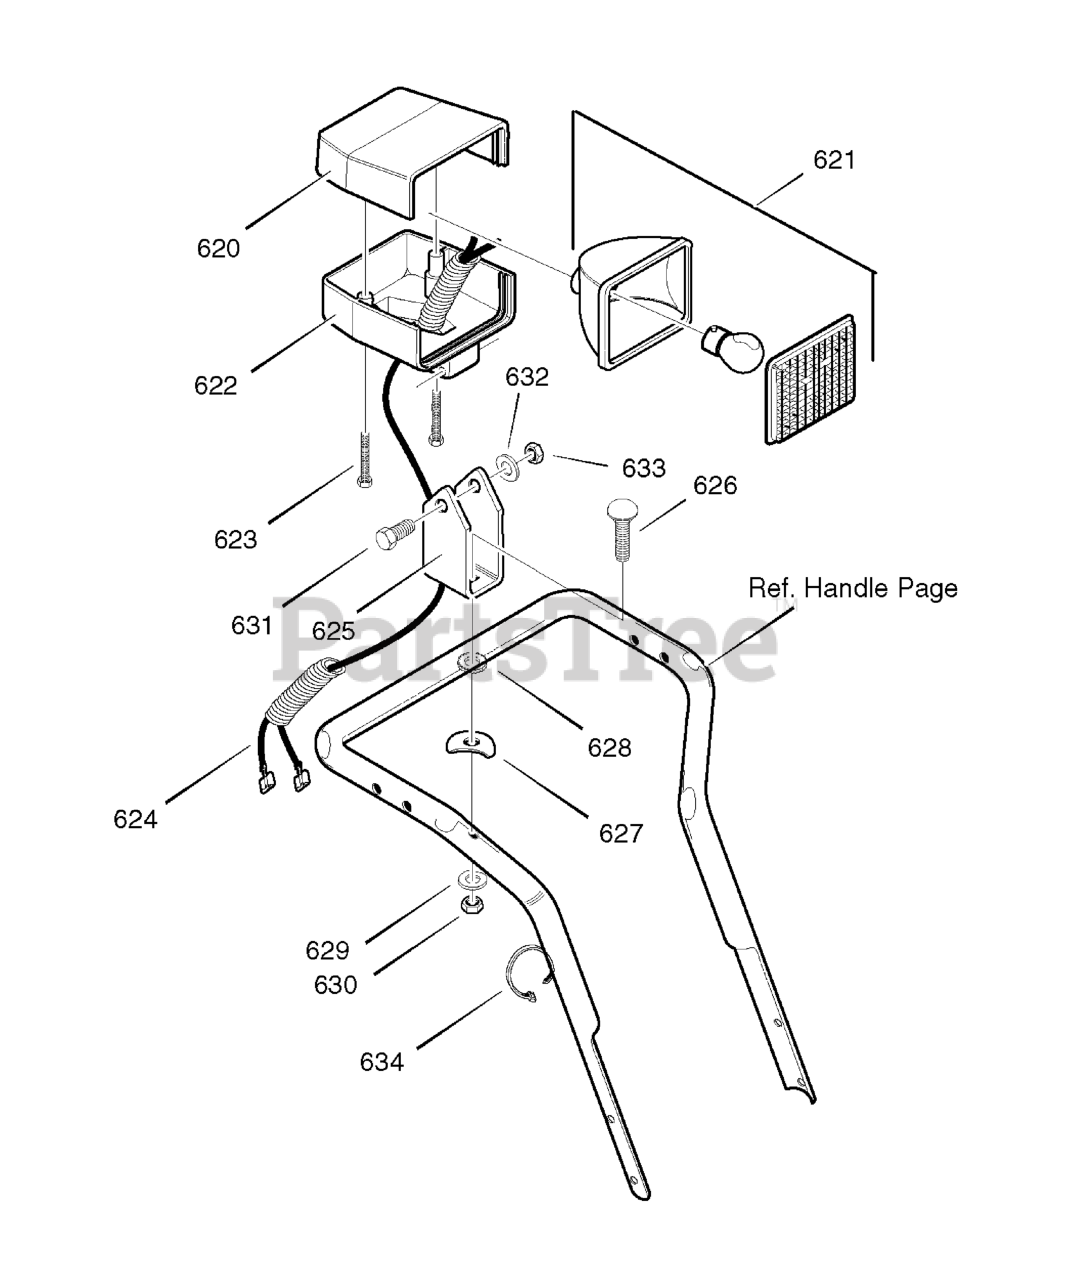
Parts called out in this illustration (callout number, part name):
620	HOUSING, HEADLIGHT UPPER
621	HEADLIGHT ASSEMBLY *
622	HOUSING, HEADLIGHT LOWER
623	SCREW, #8 X 1.75
624	WIRING HARNESS, HALOGEN
625	BRACKET, HEADLIGHT
626	BOLT, CARRIAGE - 5/16-18 X 2.00
627	WASHER, SADDLE
628	WASHER, EXLK .32 X .60 X .040
629	WASHER, SPTLK .31 X .58 X .08
630	NUT, 5/16-18 REGHEX
631	SCREW, 5/16-18 x 2.00
632	WASHER, SPTLK
633	NUT, 5/16- 18 REGHEX
634	TIE, CABLE
